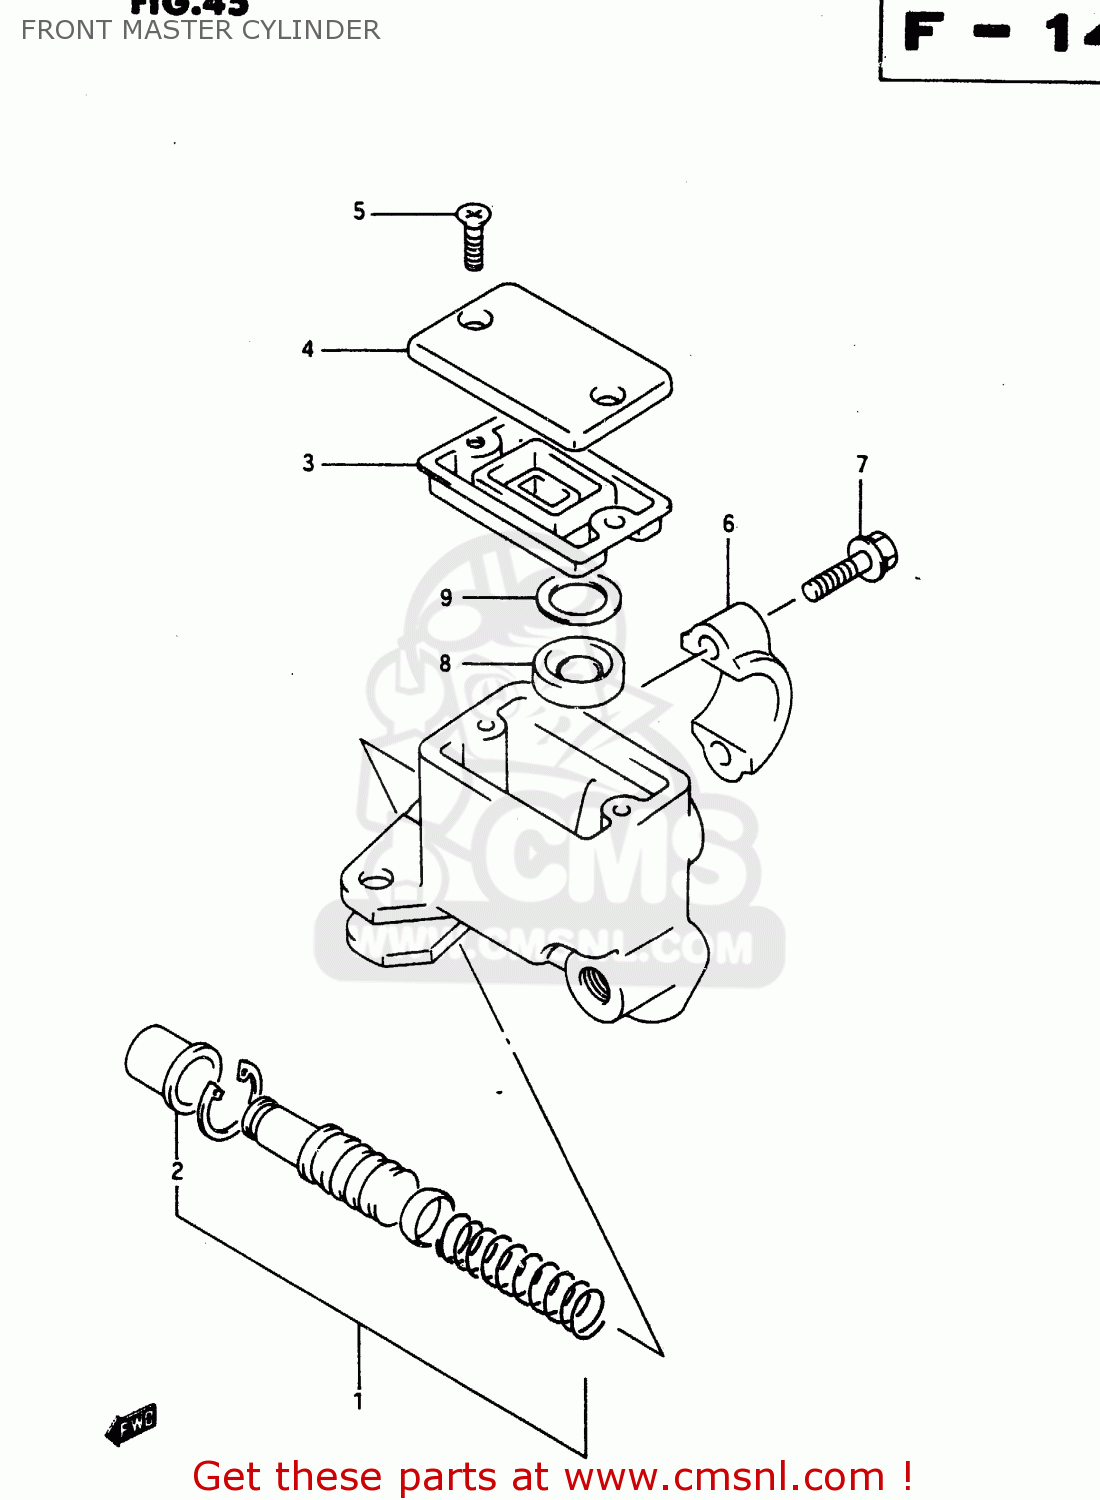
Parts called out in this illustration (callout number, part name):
1	PISTON & CUP SET
2	BOOT
3	DIAPHRAGM
4	CAP
5	SCREW
6	HOLDER
7	BOLT
8	SEPERATOR
9	PLATE
